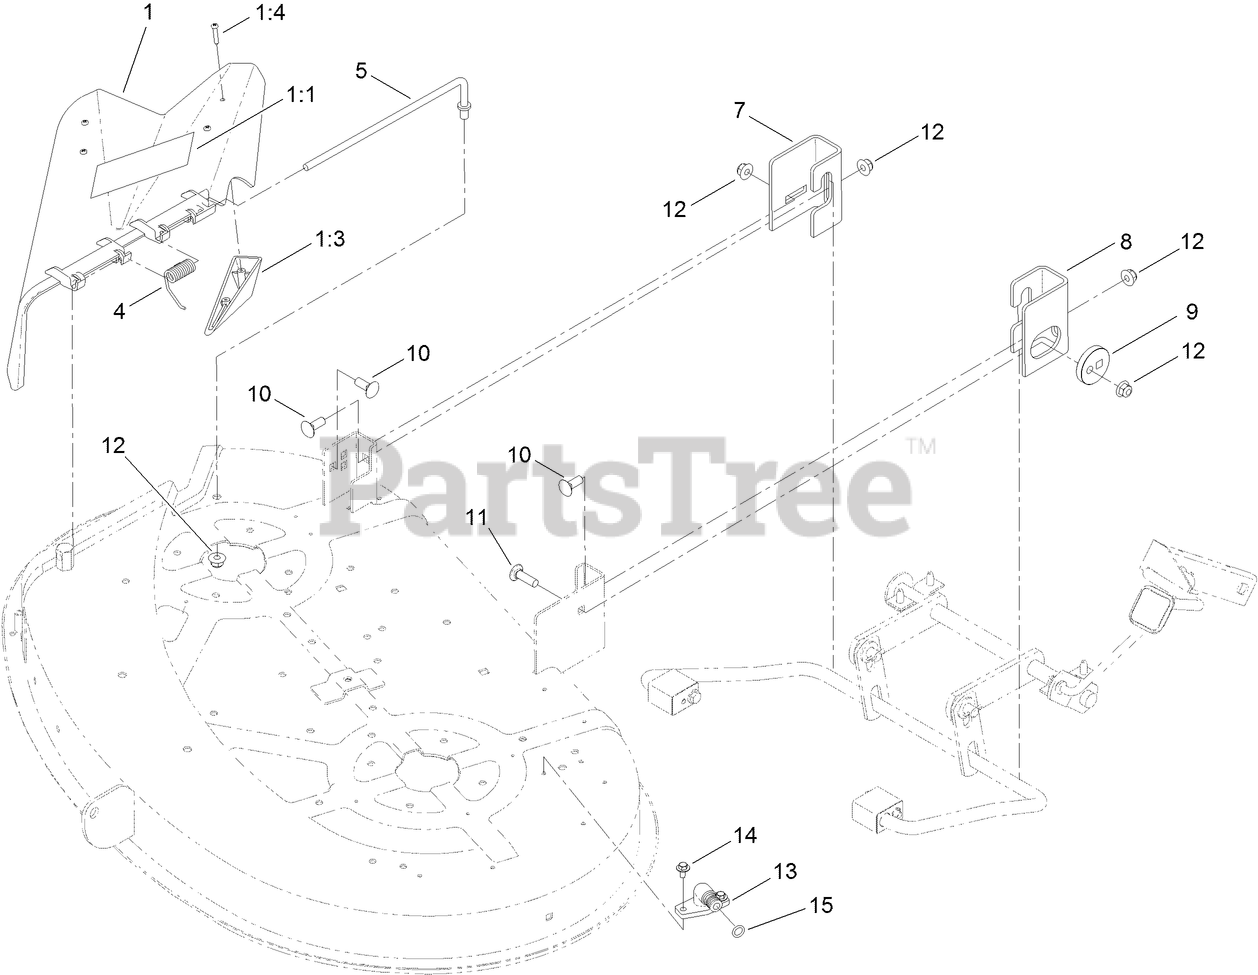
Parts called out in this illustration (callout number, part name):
1	DEFLECTOR ASM
1:1	DECAL-DANGER
1:3	KICKER
1:4	SCREW-PPH
4	SPRING-TORSION
5	ROD-PIVOT
7	BRACKET-HANGER, RIGHT REAR
8	BRACKET-HANGER, LEFT REAR
9	ECCENTRIC
10	BOLT-CARR
11	SCREW-CARR
12	NUT-HF, NI
14	SCREW-HHFTF
15	O-RING
